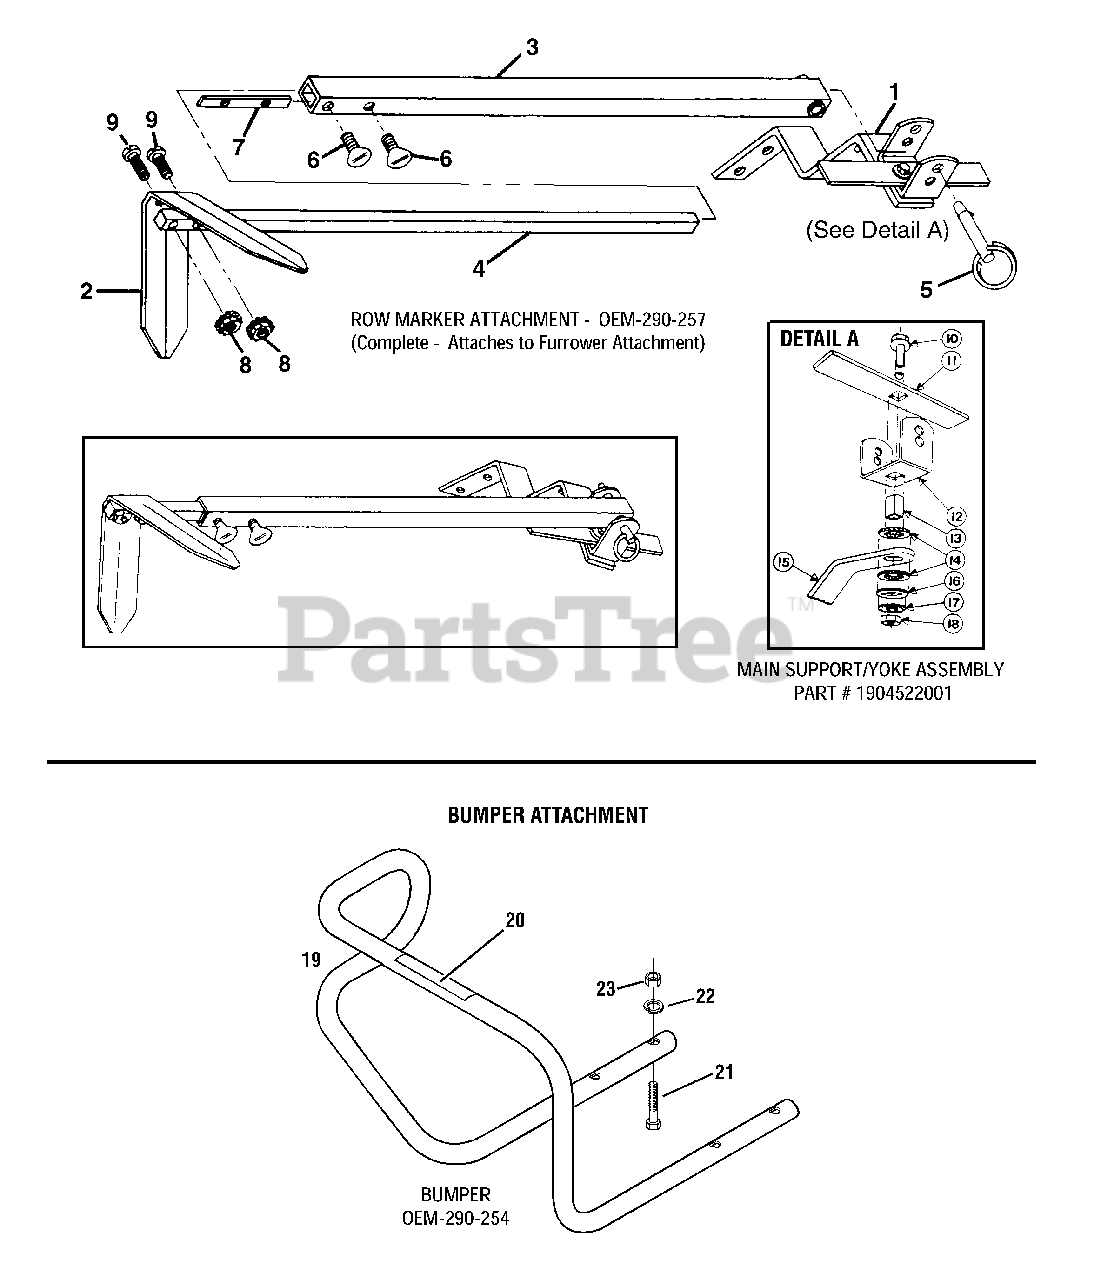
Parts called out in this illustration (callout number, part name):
1	Main Support & Yoke Assy-complete
2	Marker Blade-blade only
3	Marker Arm-main arm
4	Marker Arm-extension arm with stop pin
5	Hitch Pin
6	Thumbscrew-1/4-20 x 1/2
7	Nut Bar
8	Nut-hex, 10-24 w/attached start washers
9	Screw-round hd.,10-24 x 1
10	Screw-hex flanged locking, 3/8-16 x 1-1/2
11	Stop Bar
12	Yoke
13	Tube Key-square
14	Washer-friction
15	Main Support
16	Washer-square hole
17	Washer-disc spring
18	Nut-hex 3/8-16.
19	Bumper
20	Decal - Caution
21	Screw-hex hd., 5/16-18 x 2-1/4
22	Lockwasher-5/16
23	Nut-hex, 5/16-18
